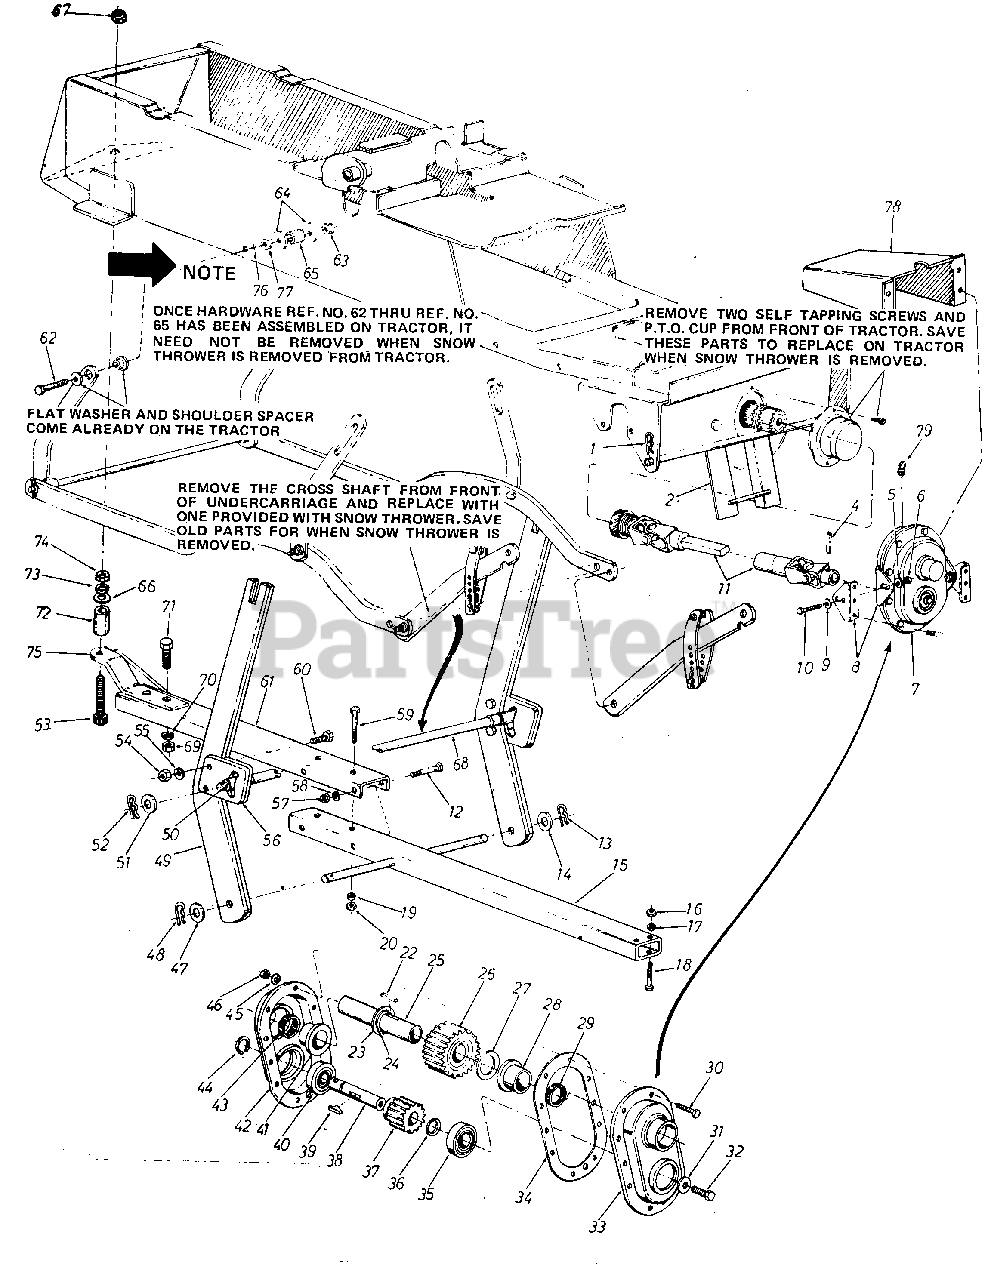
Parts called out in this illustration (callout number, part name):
1	Intern. Cotter Pin 3/4" Dia.
2	Guide Bracket Ass y.
4	Spring Pin Spirol 1/4"Dia. x Lg.
5	Belleville Wash. .341 " I.D. x.88" O.D.
6	Hex Nut 5/16-18 Thd.*
7	Gear Box Ass'y. Comp.
8	Gear Box Support Brkt.
9	Belleville Wash. .341 " I D. x .88" O.D.
10	Hex Scr 5/16-18 x .75" Lg.
11	Universal Drive Shaft Ass'y.
12	Hex Scr. 3/8-24 x 4.50" Lg.*
13	Hair Pin Cotter
14	Fl.-Wash. .62" I.D. x 1.12" 0.D.
15	Lift Shaft Ass'y.
16	Hex Ins. Jam L.-Nut 3/8-24 Thd.
17	L.-Wash. 3/8" Scr.*
18	Hex Scr. 3/8-24 x 2.75" Lg.*
19	L.-Wash. 3/8" Scr.*
20	Hex Ins. Jam L.-Nut 3/8-24 Thd.
22	Hi-Pro Key 1/4" x 7/8" Dia.
23	Fl.-Wash. 1.31" I.D. x 2.00" O.D. x .060
24	SnaP Rinq for 1.25" Dia. Shaft
25	Gear Shaft 1.25" Dia. x 6.0" Lg.
26	28 Teeth Spur Gear
27	Fl.-Wash. 1.31" I.D. x 2.00 O.D. x .060
28	Flange Bearing 1.25" I.D. x 1.75" O.D.
29	Oil Seal 1.25" I.D. x 1.75" O.D. x .26
30	Hex Scr. 1/4-28 x .88" Lg.
31	Fl.-Wash. .40 I.D. x 1.25" O.D. x.160
32	Hex L.-Scr. 3/8-24 x 1.00" Lg.
33	Complete Gear H ousing Half-L.H.
34	Gasket
35	Ball Bearing 1.00" I.D. x 2.00" O.D.
36	Fl.-Wash. 1.03" I.D. x 1.63" x . 090
37	15 Teeth Spur Gear
38	Input Shaft
39	Woodruff Key 1/4" x 3/4" Dia.
40	Ball Bearing 1.00" I.D. x 2.00" O.D.
41	Flange Bearing 1.25" I.D. x 1.75" O.D.
42	Complete Gear Housing Half -R . H .
43	Oil Seal 1.25" I.D. x 1.75 " O.D. x .26
44	Snap Ring for 1.00" Dia. Shaft
45	Spring Wash. 1/4" I.D.
46	Hex Nut 1/4-28 Thd.
47	Fl.-Wash. .62" I.D. x 1.12" O.D.
48	Hair Pin Cotter
51	Fl.-Wash. .62" I.D. x 1.12" O.D.
52	Hair Pin Cotter
53	Hex Bolt 5/8-18 x 4.00" Lg.
54	Hex Nut 5/16-18 Thd.*
55	L.-Wash. 5/16" Scr.
58	L.-Wash. 3/8" Scr.*
59	Hex Scr. 3/8-24 x 2.75"
60	Hex Scr. 5/16-18 x 1.00" Lg.*
61	Lift Bracket
62	Hex Scr. 3/8-24 x 2.50"
63	Hex Jam L.-Nut 3/8-24 Thd.
64	Fl.-Wash...375 I.D. x 1.00" O.D. x . 1 35"
65	Spacer .275 I.D. x .625 O.D. x .440
66	Fl.-Wash. .66" I.D. x 1.25" O.D. x .100
67	Hex Jam L.-Nut 5/8-18 Thd.
68	Cross Shaft Ass'y.
69	Hex Nut 1/2-13 Thd.*
70	L.-Wash. 1/2" Scr.*
71	Hex Scr. 1/2-13 x 1.25"
72	Bushing
73	L.-Wash. 5/8" Scr.*
74	Hex Jam Nut 5/8-18 Thd.
77	H ex ut 3/8-24 Thd.*
78	Drive Shaft Cover
79	Grease Fitting
